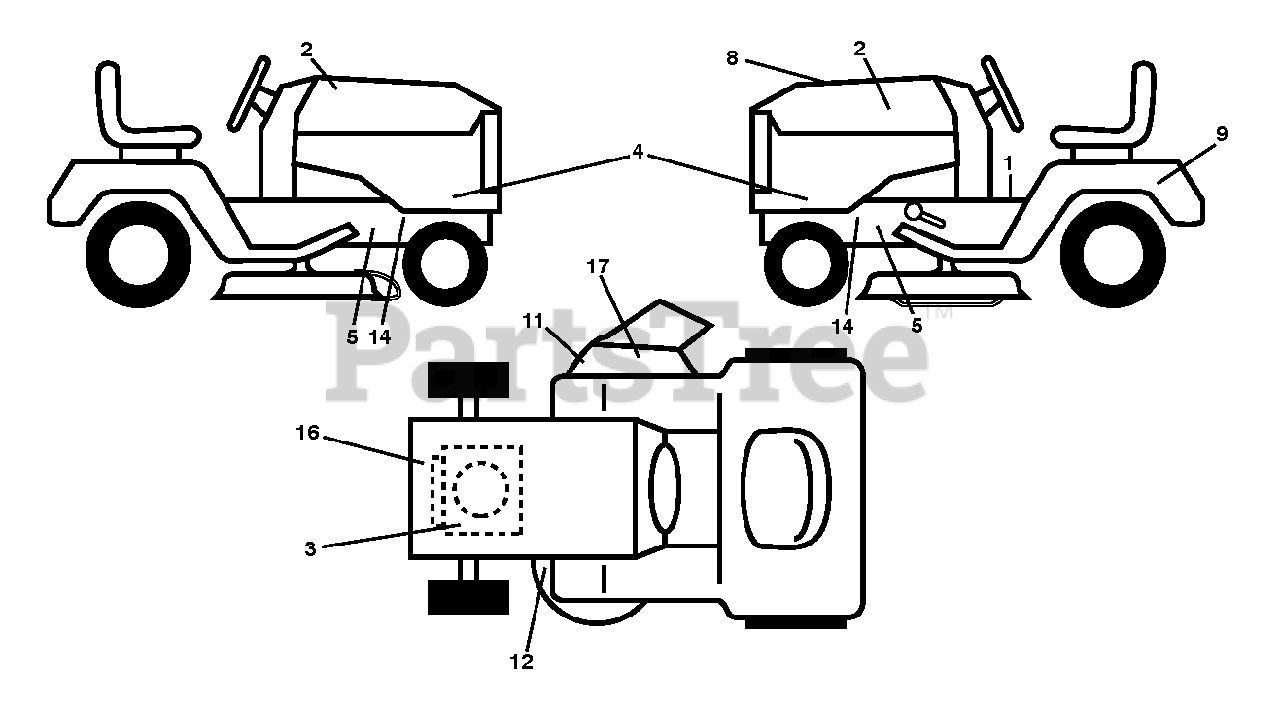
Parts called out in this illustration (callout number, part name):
1	Decal, Tractor Saddle
2	DECAL.BADGE.170MM.TEXTLOGO.
3	DECAL.ENGINE.WARNING
4	DECAL.SDPNL.TS38
5	DECAL.CHASSIS.HOT.MUFFLER
8	DECAL.RPL.BSM21.PB.TLW.38.PMST
9	DECAL BTRY SYMBOLS
11	DECAL.DFLCTR.WARNNG.CTFNGR.SYM
12	DECAL.DECK.SCH.36,38,94.NONCR
14	DECAL.WARNING.SERVCE/FIRE
16	DECAL.ENG.BS.3125SER.PB.279738
17	DECAL, DECK DEFLECTOR, WARNING
